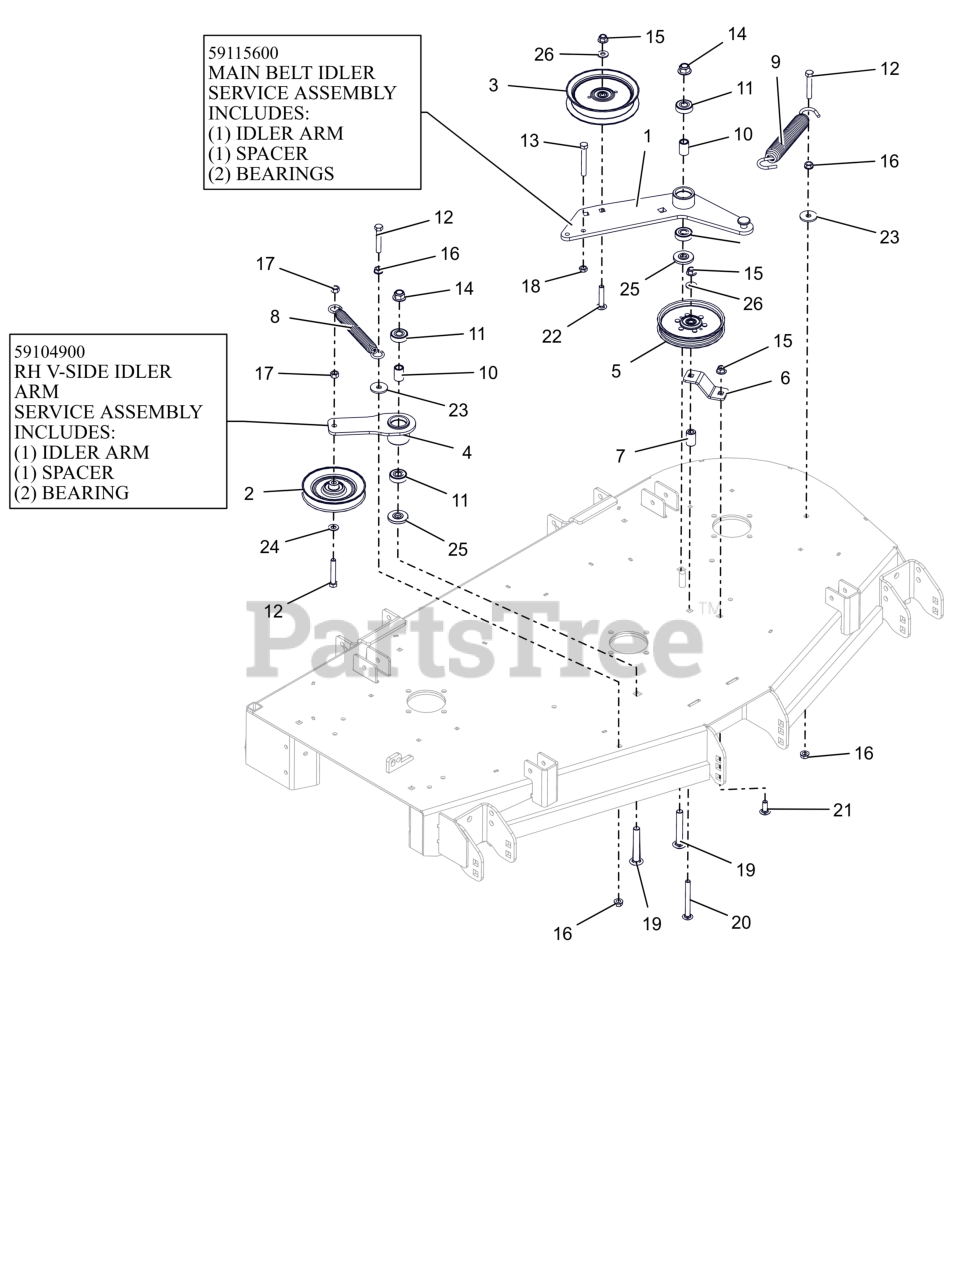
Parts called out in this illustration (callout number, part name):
1	WLDMT, DECK PTO IDLR ARM
1	ASSEMBLY, MAIN BELT IDLER
2	IDLER, V-5.00"
3	IDLER, FLAT 5.00"
4	WLDMT, DECK RH IDLER ARM
4	RH V-SIDE IDLER ARM ASSEMBLY
5	PULLEY, FLAT IDLER
6	PTO FIXED IDLER MTG BRKT -RED
7	BUSHING, SLV .380X.750X1.190
8	SPRING, EXTENSION
9	SPRING, EXTENSION
10	SPACER .510 X .75 X 1.1485
11	BRG-BALL .500X1.38X.437
12	BLT,HEX .38-16X2.25 G5 ZCC
13	BLT, HEX .38-16X2.75 G5 ZCC
14	NUT,NYL-FLG .50-13 GF ZCC
15	NUT,NYL-FLG .38-16 GF ZCC
16	NUT, SPNLK-FLG .38-16 G5 ZCC
17	NUT-LK-CTR .38-16 ZC120
18	NUT-JAM .375-16 G2 ZCC
19	BTL,RHSSN .500-13 X 3.25 G5 ZCC
20	BLT,RHSSN .38-16X3.50 G5 ZCC
21	BLT,RHSSN .38-16X1.00 G5 ZCC
22	BLT,RHSSN.375-16X2.00 G5 ZCC
23	WSHR,FLT .406X1.375X.135 ZCC
24	WSHR,FLT .406X.812X.065 ZCC
25	SPACER, IDLER ARM
26	WSHR,FLT .375X.875X.083 ZCC
